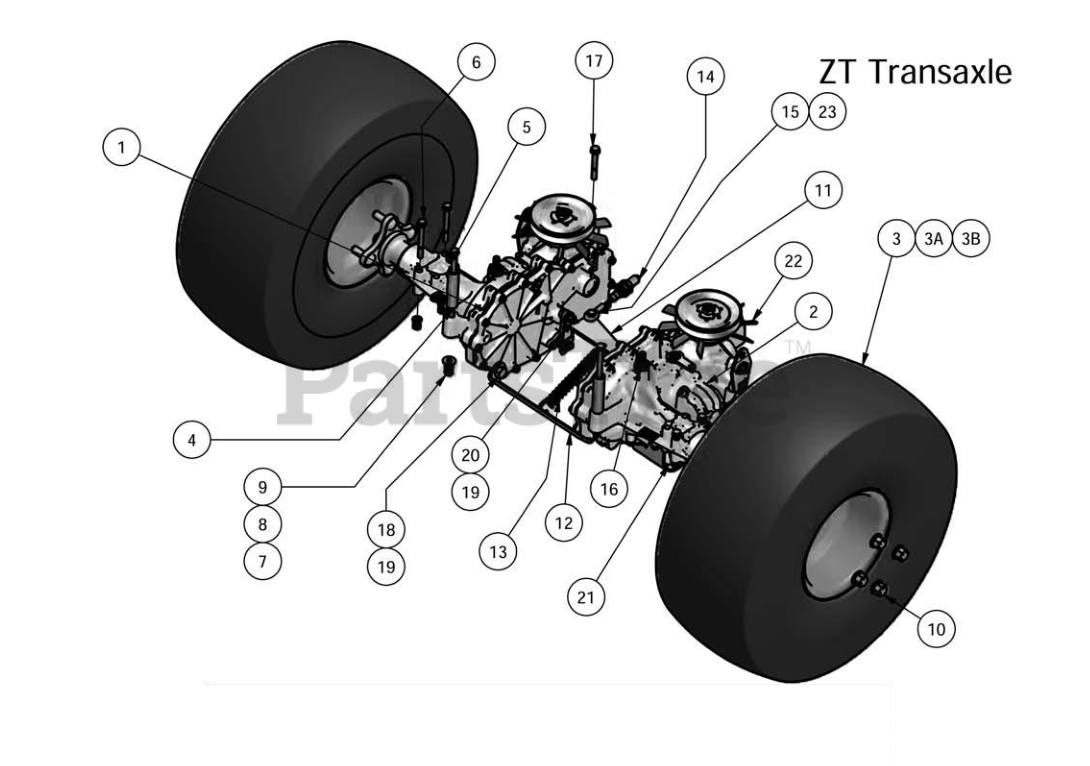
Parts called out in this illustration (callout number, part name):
2	Axle-Right
3	20 X 10-8 Tire & Wheel Assembly
3A	20 X 10-8 Tire (Only)
3B	8" ZT Orange Rim
4	3 1/4" Transaxle Spacer
5	5/16" x 6" Bolt
6	5/16" x 3" Hex Bolt
7	5/16" Flat Washer
8	5/16 Lock Washer
9	5/16 Hex Nut
10	1/2" Lug Nut
11	Crossover Brake Bracket
12	Transaxle support
14	Brake Cable
15	1/4" x 3/4" Hex Bolt
16	45 degree fitting
17	5/16" x 2 1/2" Hex Bolt
18	3/8" x 2" Hex Bolt
19	3/8" Nylock Nut
20	1/4" x 1" Hex Bolt
21	Transaxle Filter
22	Fan/Pulley Kit
23	1/4" Nylock Nut
